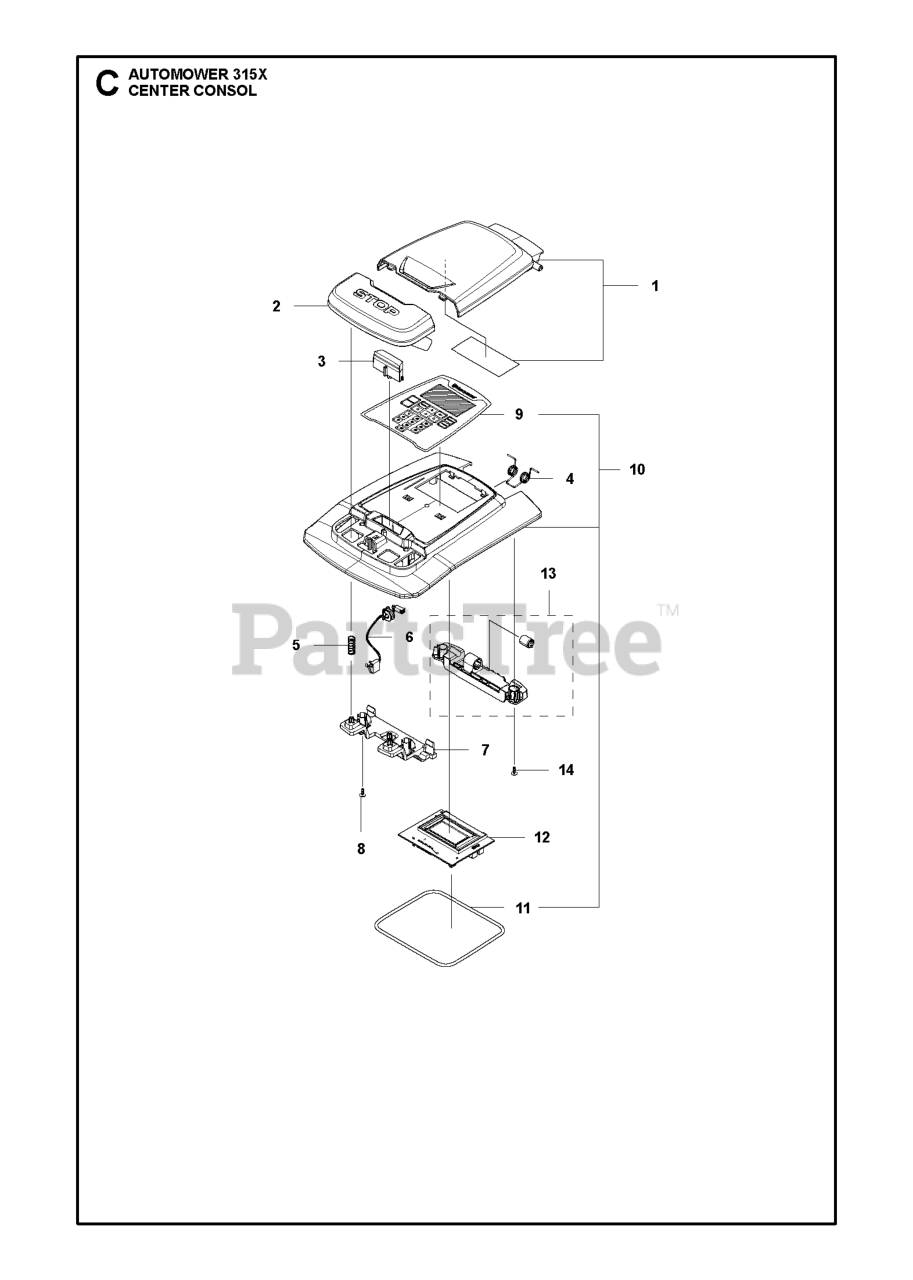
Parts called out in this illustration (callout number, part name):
1	HATCH KIT BLACK
2	BUTTON STOP
3	LOCK
4	TORSION SPRING DT=1,3MM
5	SPRING LOCK STOP BUTTON
6	SWITCH STOP BUTTON NO ANCHOR
7	SUPPORT REAR
8	SCREW 14MM
9	KEYBOARD 2.8" DISPLAY
10	COVER KIT BLACK
11	SEALING STRIP P15 UPPER
12	PRINTED CIRCUIT ASSY HMI BOARD
13	SUPPORT KIT
14	SCREW 14MM
